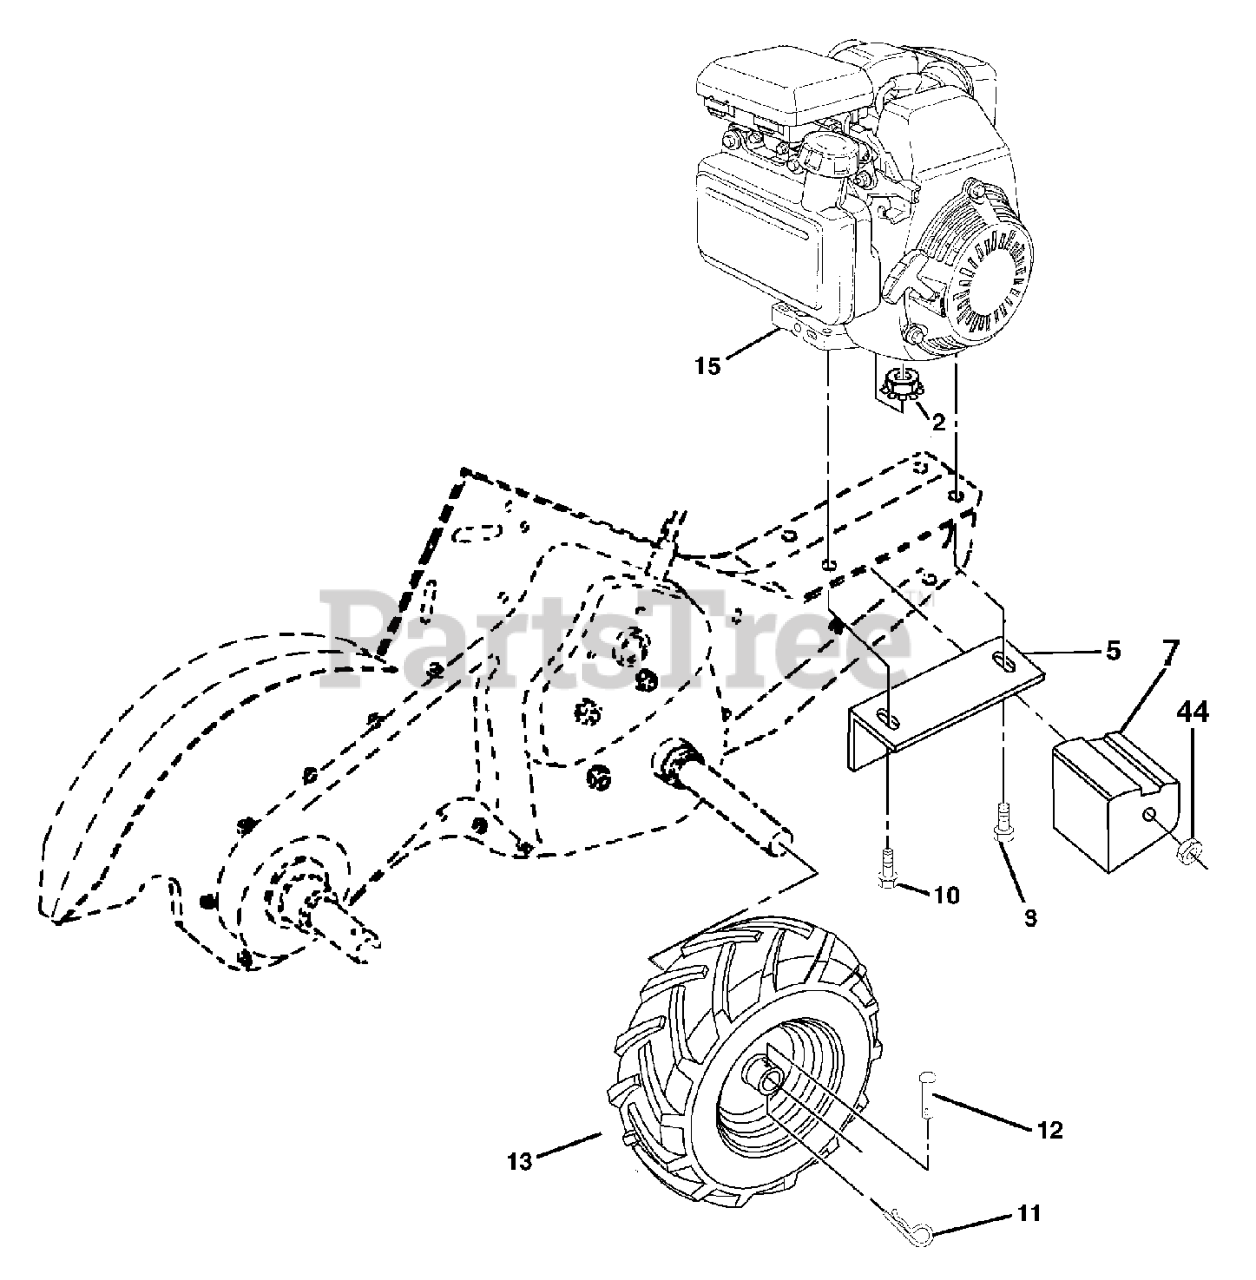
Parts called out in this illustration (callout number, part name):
2	LOCKNUT-FLANGE 5/16-18
5	BRACKET.REINFORCEMENT.RH.BLACK
7	COUNTERWEIGHT.RH
9	BOLT, HEX 5/16-18X1-3/4
10	BOLT
11	RETAINER M
12	RIVET
13	WHEEL.ASM.DRT.13X5-6.RT.SILVER
